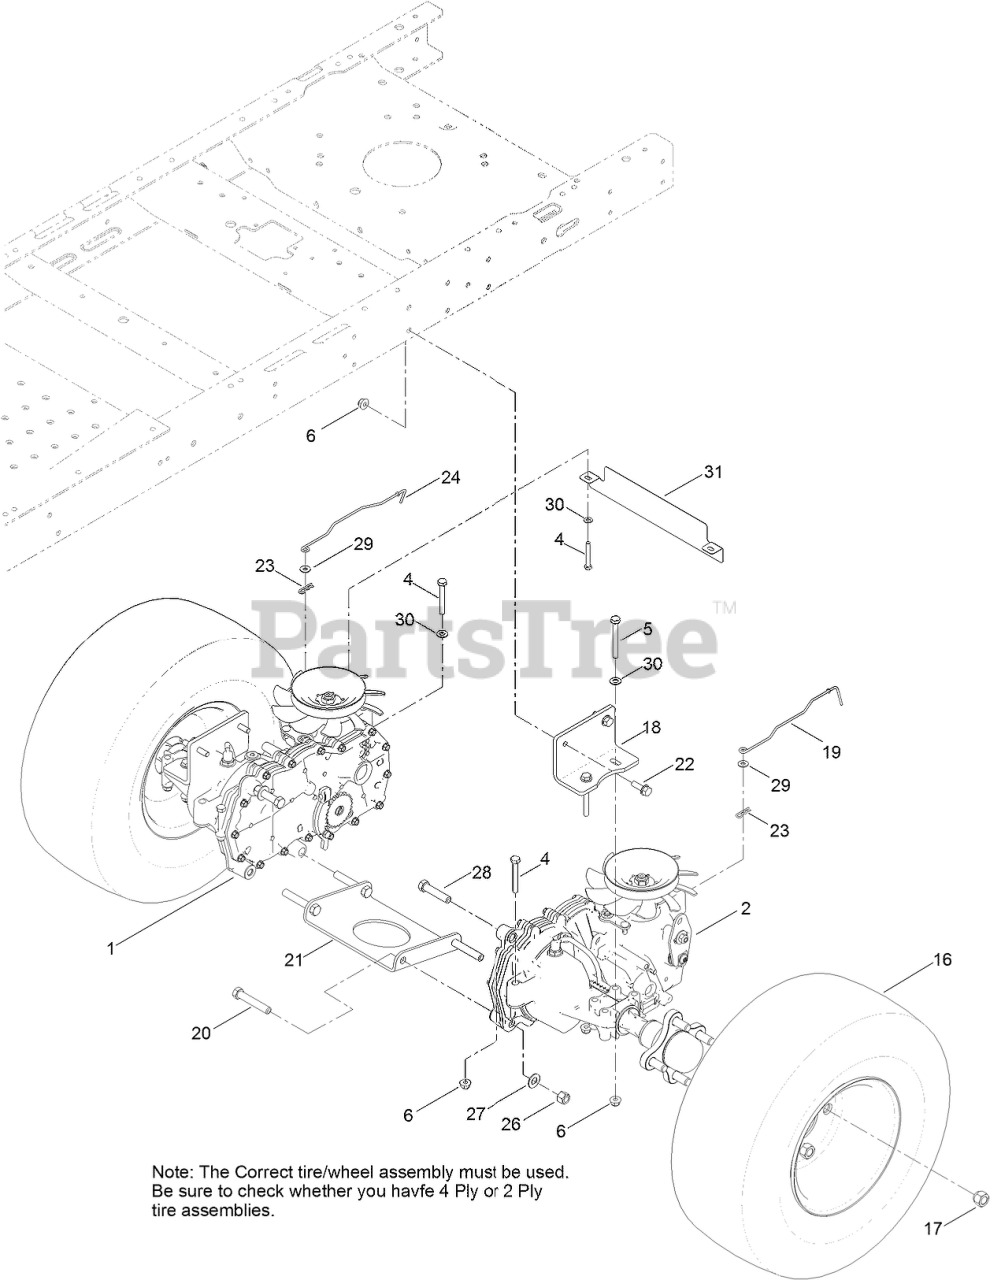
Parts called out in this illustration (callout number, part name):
1	RH HYDRO TRANSAXLE ASM
2	LH HYDRO TRANSAXLE ASM
4	SCREW-HH
5	SCREW-HH
6	NUT-HF, NI
16	4 PLY WHEEL AND TIRE ASM
16	2 PLY TIRE AND WHEEL ASM
17	NUT-LUG
18	MOUNT-HYDRO
19	ROD-BYPASS, LH
20	SCREW-HH
21	PLATE-CROSS, HYDRO
22	SCREW-HHF
23	PIN-COTTER
24	ROD-BYPASS, RH
26	NUT-LOCK, NI
27	WASHER-FLAT
28	SCREW-HH
29	WASHER
30	WASHER-PLAIN
31	GUARD REAR, WIDE
